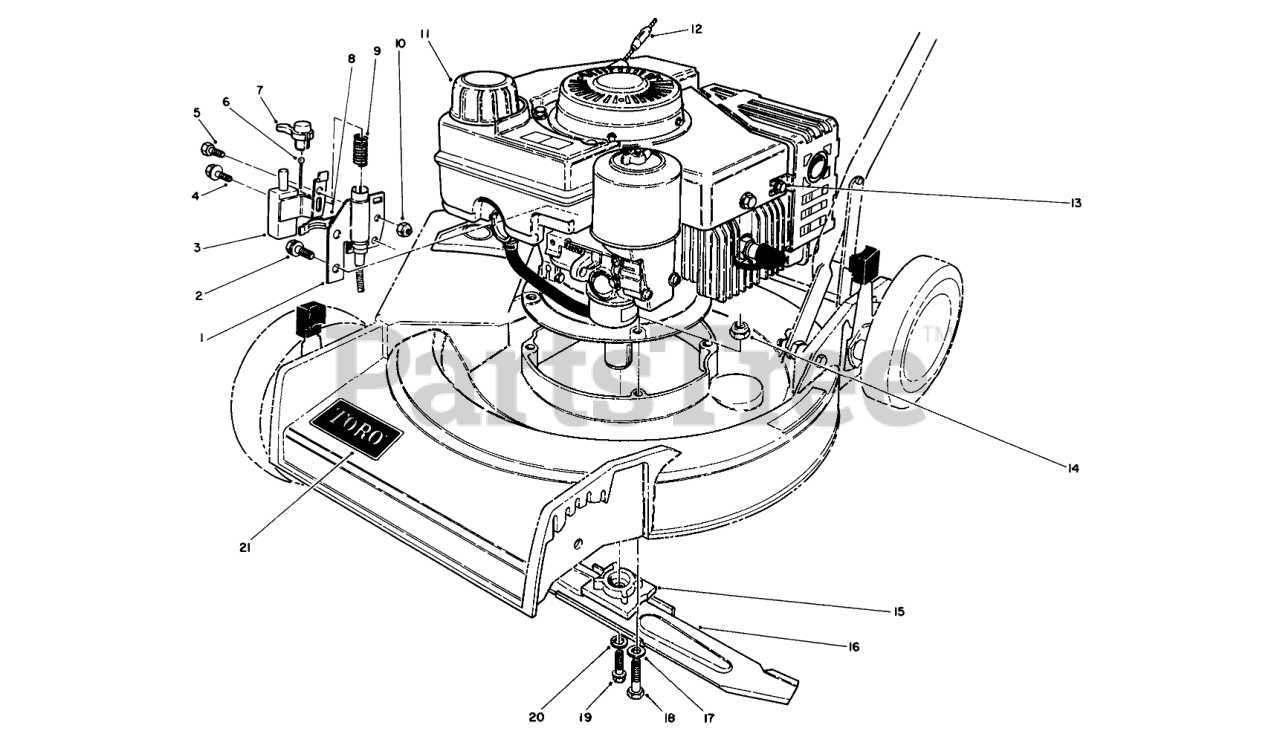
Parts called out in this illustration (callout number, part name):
1	TUBE WA
2	SCREW
3	PUSH BUTTON SWITCH
4	SCREW
5	SCREW-HH
6	Cable Brake (Ref.)
7	BRAKE PAD/PLUNGER ASM
8	CABLE CLAMP
9	COMP SPRING
10	NUT-LOCK, NI
11	Engine (2 cycle)
12	Recoil Stop (Ref.)
13	SCREW-HH
14	NUT-LOCK, NI
15	BLADE RETAINER
16	Blade
17	WASHER-FLAT
18	SCREW-HH
19	SCREW-HH
20	WASHER-LOCK
21	DECAL
